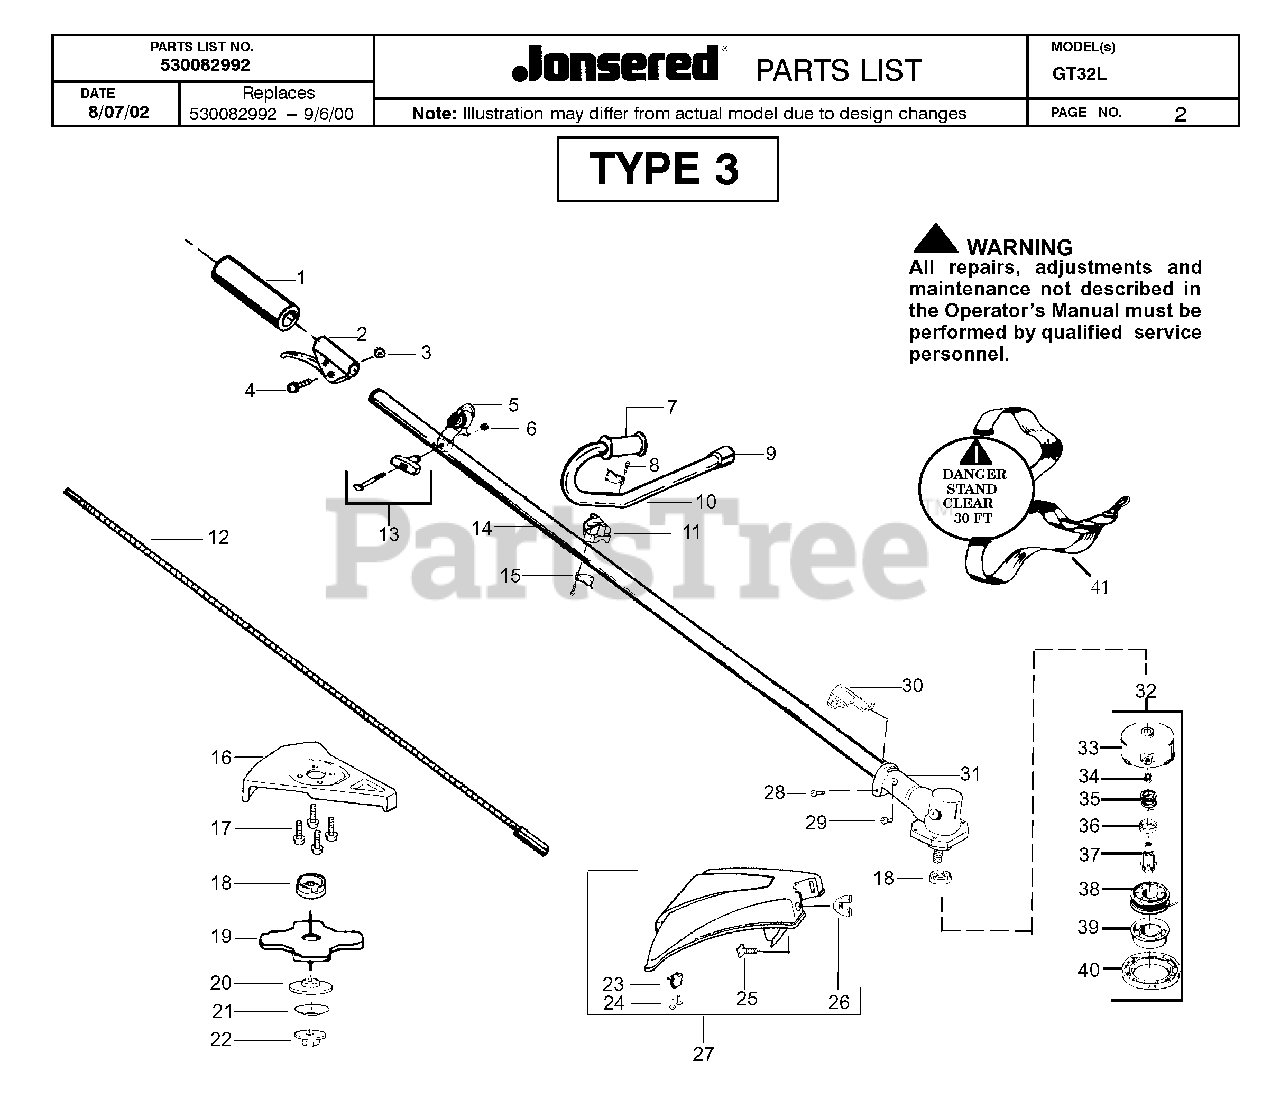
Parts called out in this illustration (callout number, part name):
1	DRIVE SHAFT GRIP
2	ASSY-THROTTLE HOUSING
3	LOCKNUT-HEX 10-24
4	SCREW-10-24 X 1" (UNC)
5	ASSY-CLAMP HARNESS
9	END CAP NLA
11	CLAMP-HANDLEBAR
13	KIT "T" HANDLE
15	BRACKET-HANDLEBAR
16	KIT,BLADE SHIELD
17	SCR 10-24 MS LDK PAN PH
20	WASHER,BLADE RETAINING
22	NUT-FLANGE (LH)
23	LINE LIMITER 17"
24	SCREW-10-16 X 1/2, TYPE 2
25	BOLT, TYPE 2
27	SHIELD KIT ASS'Y, TYPE 2
28	SCREW - CARB. ADAPTOR
30	BRACKET,SHIELD
32	TAP-N-GO I CCW
33	ASSY-HUB W/LN SAVER
34	SAVER-LINE
36	CAP-SPRING
39	TAP BUTTON
41	STRAP-SHOULD.W/WARNING
530056335	DECAL,BLADE DIRECTION
